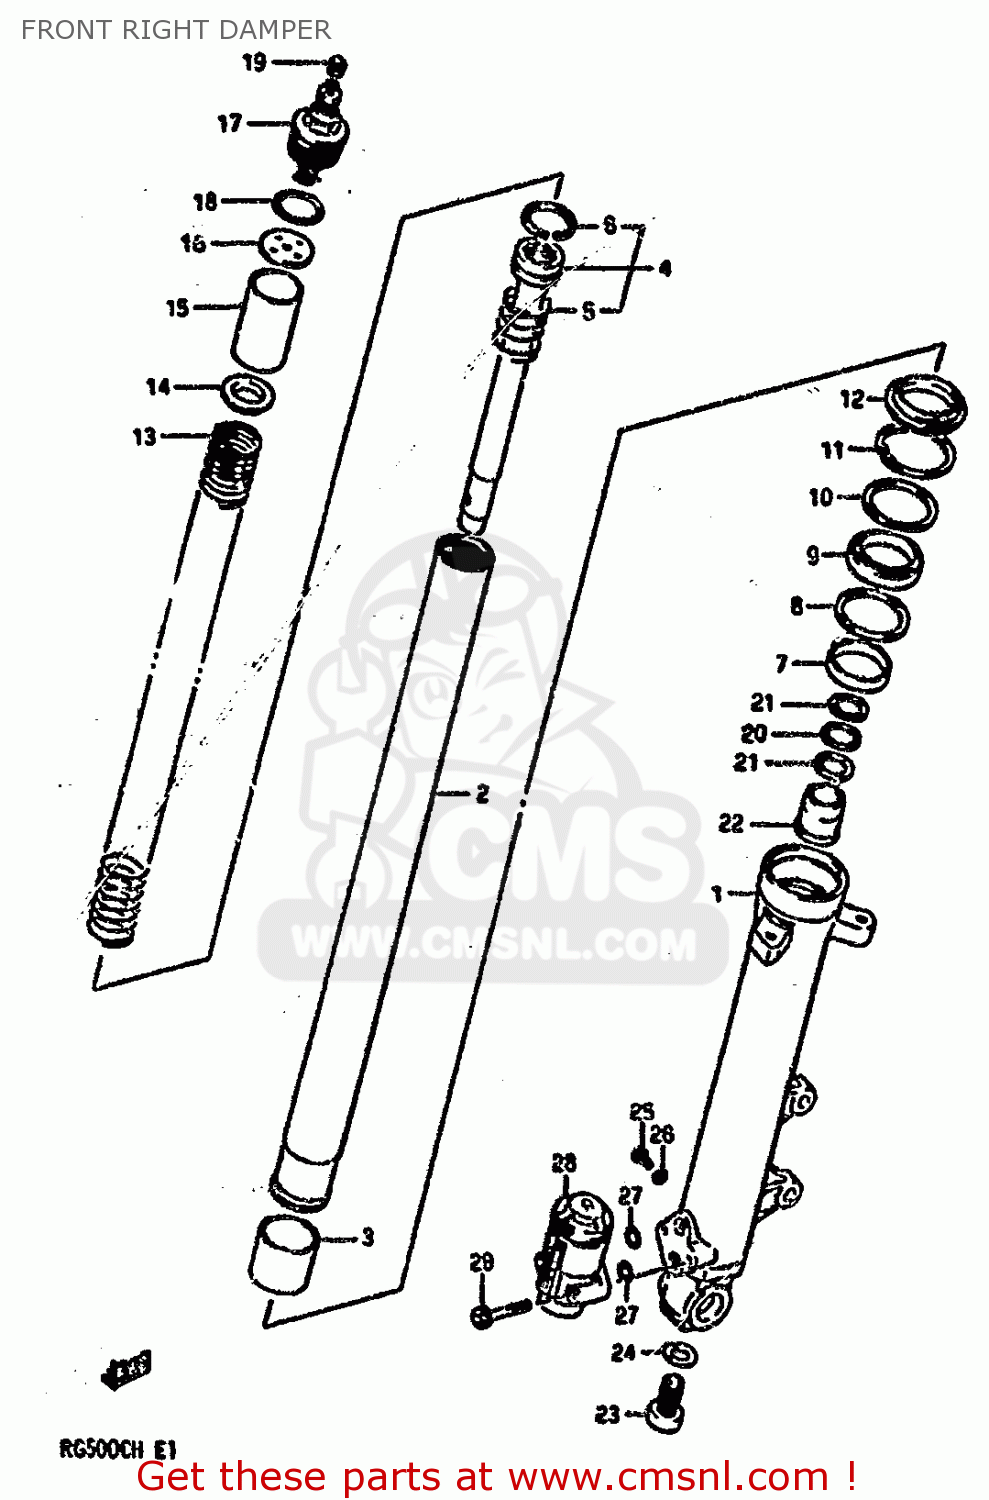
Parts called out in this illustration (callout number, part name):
1	TUBE,OUTER RH
2	TUBE,INNER
3	PISTON
4	CYLINDER
5	SPRING,REAR CUSHION
6	RING,PISTON
7	METAL,SLIDE
8	WASHER(40X50X2.3)
9	SEAL,OIL
10	WASHER,OIL SEAL
11	RING,STOPPER
12	SEAL,DUST
13	SPRING
14	GUIDE,SPRING
15	SPACER,FRONT FORK SPRING
16	WASHER
17	CAP
18	O RING
19	CAP,VALVE AIR
20	WASHER
21	SPRING,LEAF
22	PIECE,OIL LOCK
23	BOLT,CYLINDER
24	GASKET,CYLINDER (NAS)
25	SCREW
26	GASKET,DRAIN,PLUG (NAS)
27	O RING
28	PDF ASSEMBLY
29	BOLT
